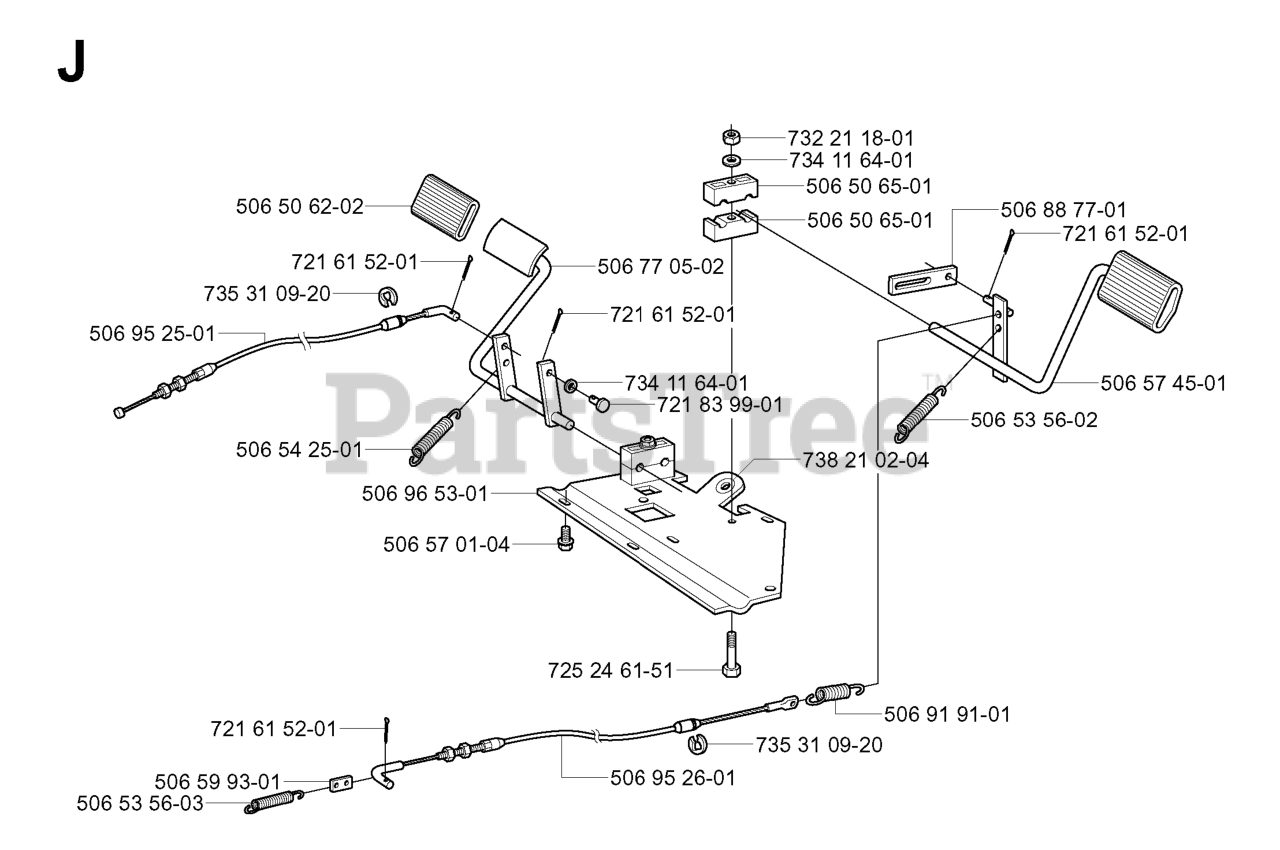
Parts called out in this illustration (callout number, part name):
480	HSNG, ASSY AUG 21"
490	BLADE, SCRAPER 20.88 P
492	SCREW, 1/4-20X.63 SLTRMA
493	NUT 1/4-20
511	BEARING, FLANGE
514	WASHER, FLAT .281X .63X.
515	NUT 1/4-20
520	AUGER ASSY COMP 21"
530	BEARING & PLATE ASSY
532	SCREW, 1/4-20X .75 HHC
533	WASHER, FLAT .281X .63X.
534	NUT, 1/4-20 REGHEXCTRLK
540	SPACER, SLEV .640X.88X.732
541	PULLEY, V3L 6.00 X .75 20GA
